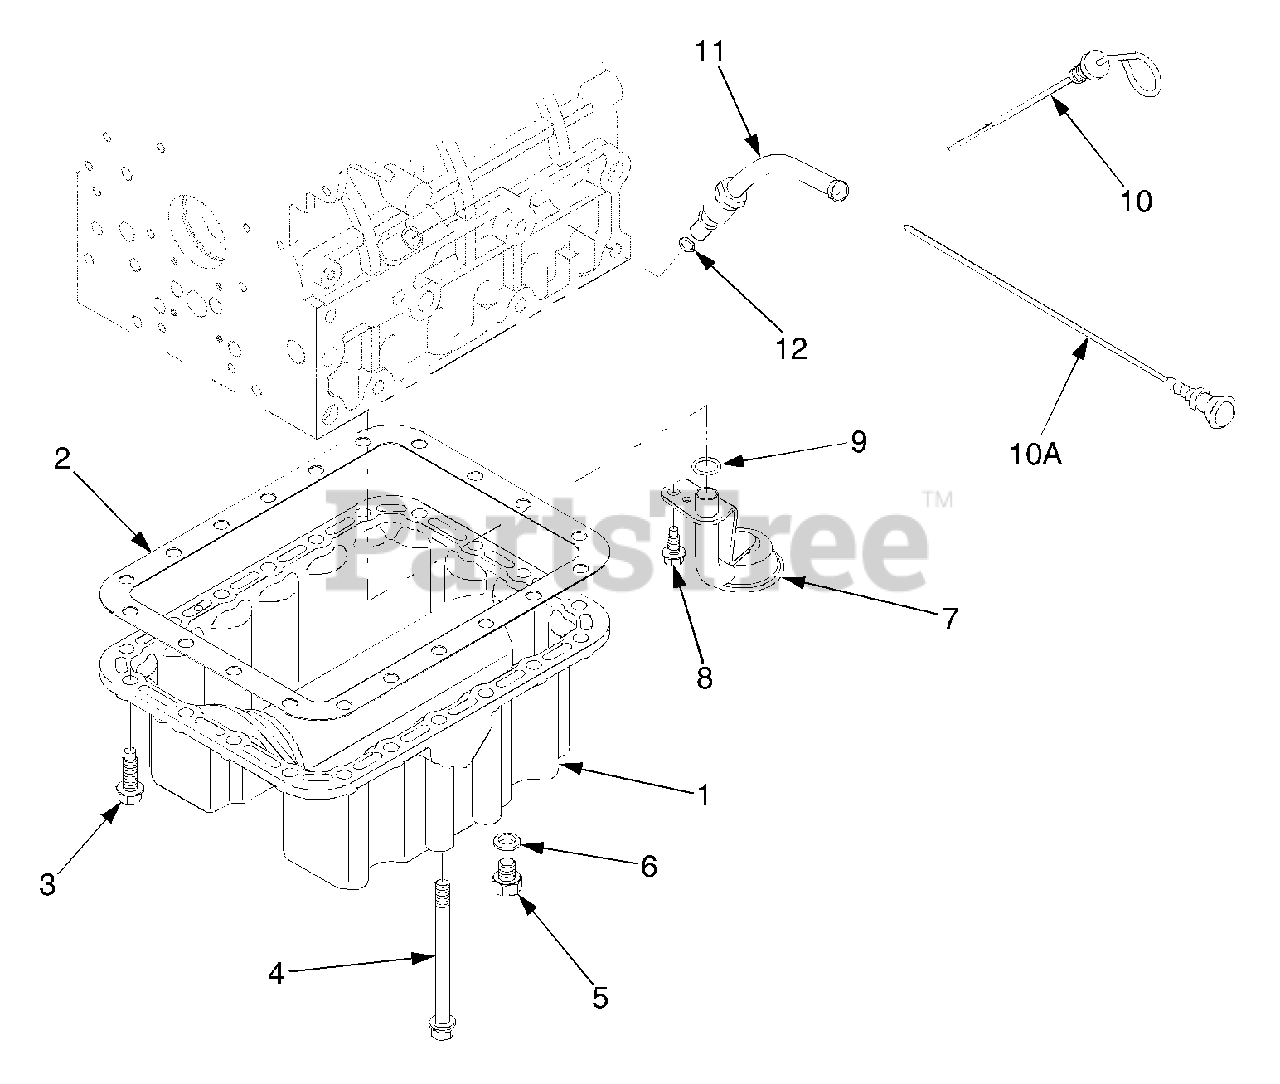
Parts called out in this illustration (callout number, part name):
1	Oil Pan Ass'y
2	Gasket, Oil Pan
5	Plug, Drain
7	Filter 1, Oil
10	Gauge, Oil
10A	Gauge, Oil
11	Guide, Oil Gauge Pipe
12	Packing
